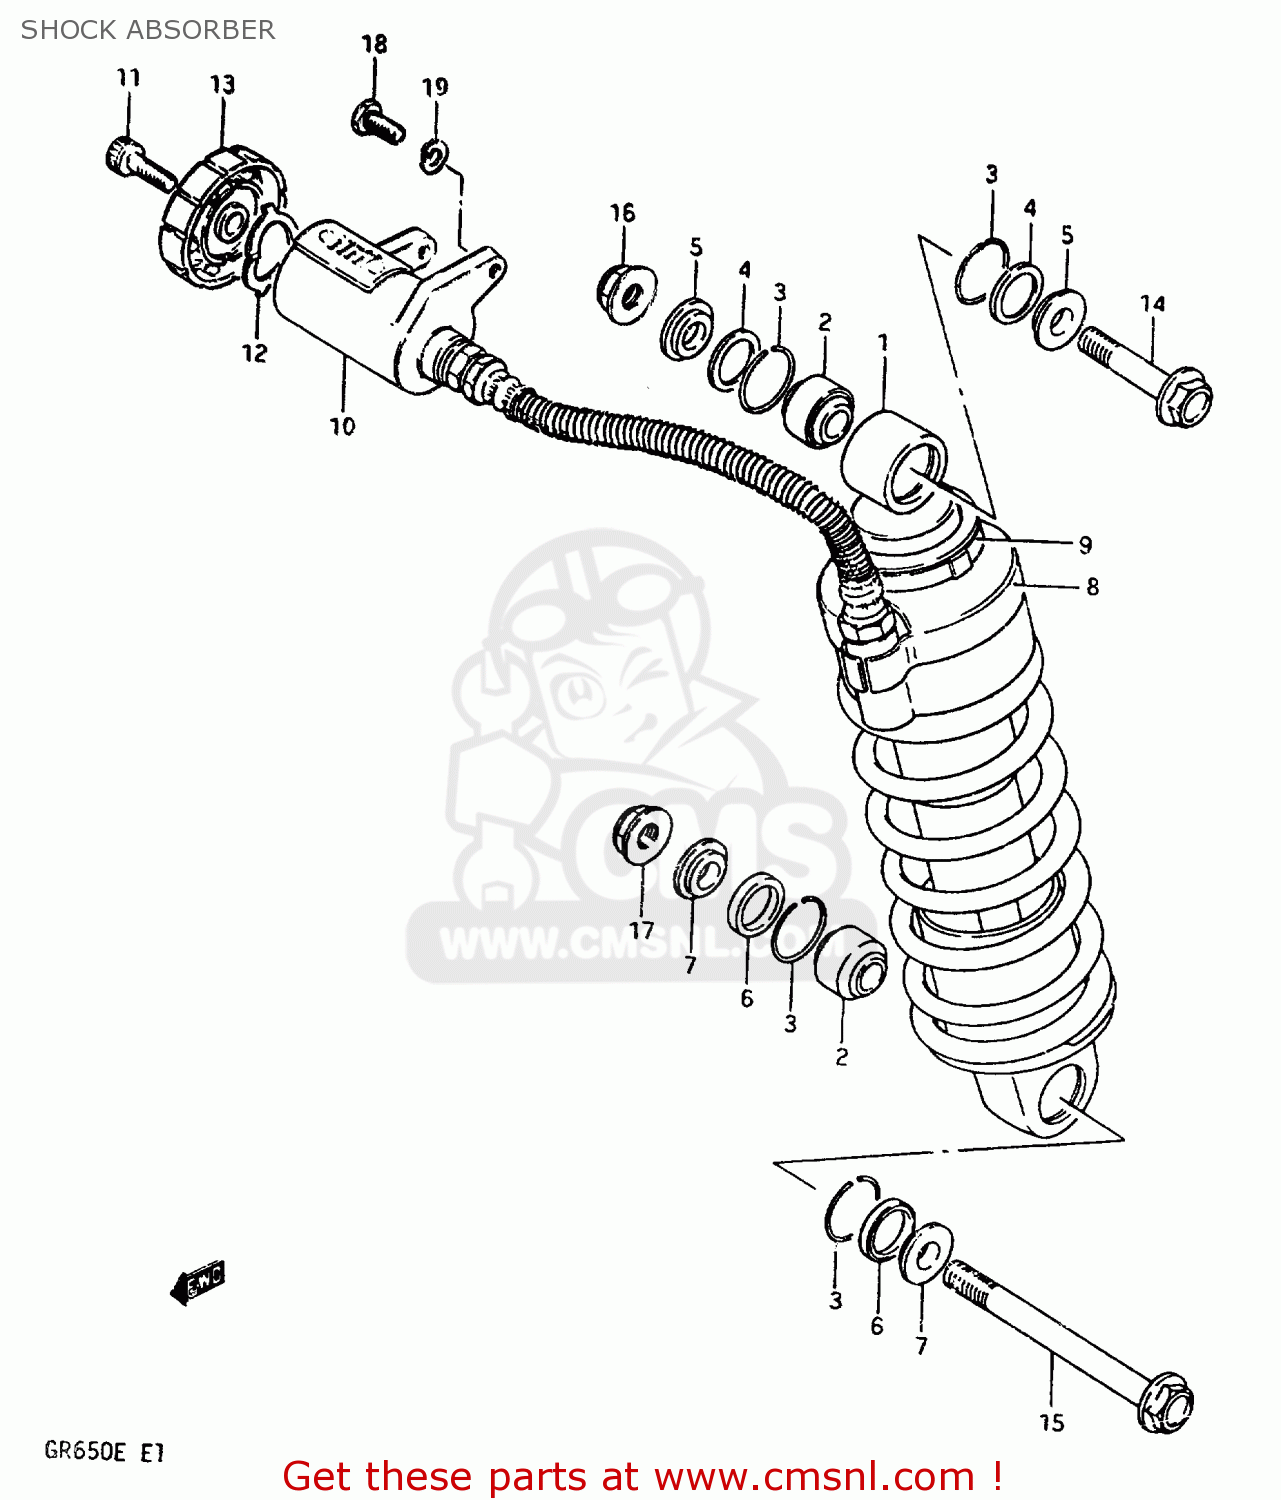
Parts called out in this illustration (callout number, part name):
1	ABSORBER ASSEMBLY,REAR SHOCK
2	BEARING
3	RING
4	DUST SEAL
5	SPACER
6	SEAL,DUST
7	COLLAR
8	COVER
9	BAND
10	SPRING ADJUSTER
11	BOLT
12	PLATE SET
13	LEVELING PLATE
14	BOLT(10X50)
15	BOLT(10X120)
16	NUT
17	NUT 10MM
18	BOLT 6X16
19	LOCK WASHER
